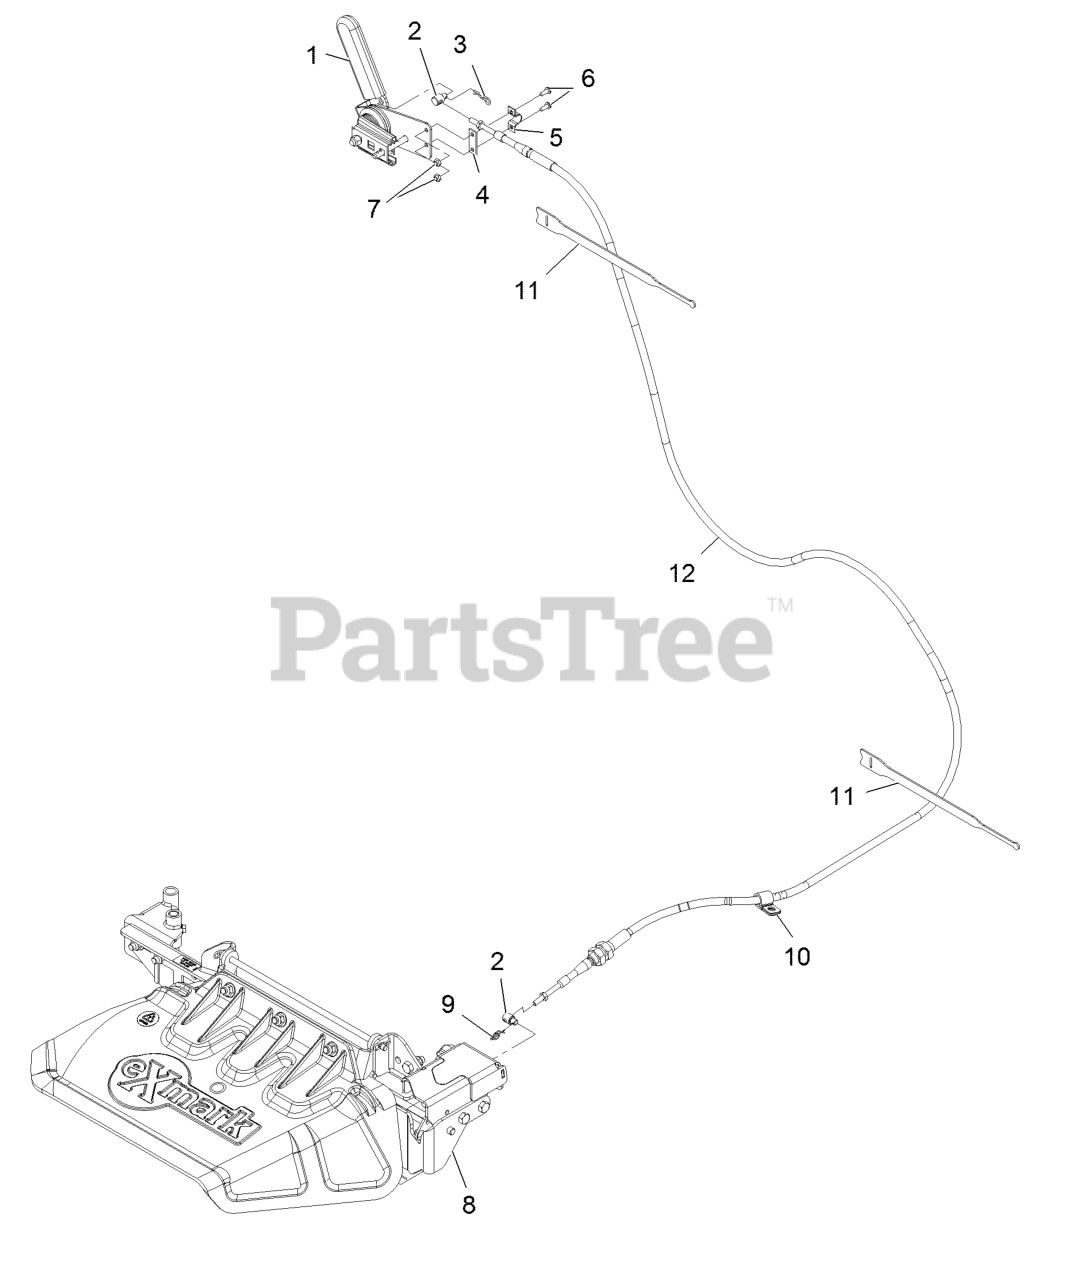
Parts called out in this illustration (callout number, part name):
1	ASM, Hand Lever
2	Pivot, Control Cable
3	Hairpin-Cotter
4	Shim,Control Cable
6	Screw-PPH #10-24 X 1/2
7	Nut-Nyloc #10-24 Thin
8	ASM, Ocd
9	Pin-Cotter, Locking
10	Clip-Loom
11	Strap-Velcro, Cable Tie
12	Cable-Discharge Gate
